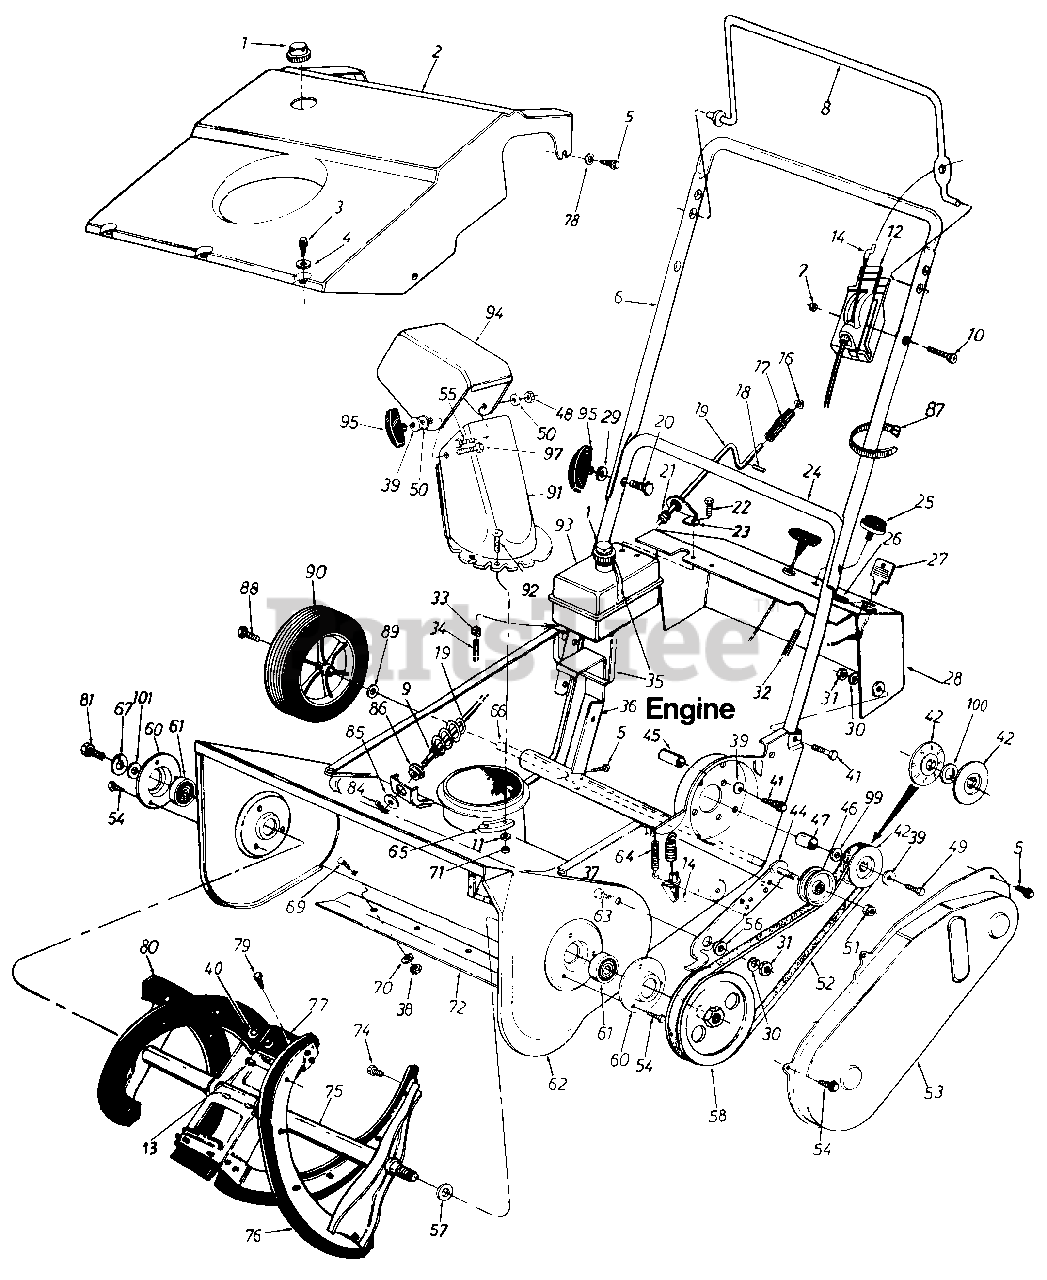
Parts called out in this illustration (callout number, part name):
1	Gas Tank Cap
2	21" Shroud
3	Hex B-Tap Scr. #10 x .38"
4	Spr.-Wash. .206" I.D. x .448"
5	Hex L-Wash. Hd. AB-Tap 1/4 x .62" Lg.
9	Fl-Wash. .385" I.D. x .62"
10	Oval C-Sunk Mach. Scr.
11	Fl-Wash. .281" I.D. x .5" O.D.
12	Throttle Body
13	Pop Rivet .187" Dia.
14	Clutch Cable 35" Lg.
16	Push Cap 3/8" Rod
17	Knob-3/8" Dia. Hole
18	Roll Pin 1/8" Dia. x .63" Lg.
19	Chute Crank Ass'y.
20	Curved Carriage Bolt 5/16-18 x 1.75" Lg.
21	Chute Crank Grommet
22	Hex AB-Tap Scr. 1/4 x .75" Lg.
23	Upper Chute Crank Brkt.
26	Plastic Plug
27	Plastic Key (Tech. Eng.)
28	Dash Panel Ass'y.
29	Saddle Wash. .320" I.D. x .937" O.D.
30	L-Wash. 5/16" I.D.
31	Hex Nut 5/16-18 Thd.
32	Primer Hose-11" Lg.
33	Hose Clamp-1/2" Dia.
34	Gas Line-15" Lg.
35	Cable Tie-17.75" Lg.
38	Hex Jam Nut 1/4-20 Thd.
39	Bell-Wash. 5/16" I.D.
40	Torx AB-Tap Scr. 1/4 x .62" Lg.
41	Hex Bolt 5/16-18 x 1.5" Lg.
42	3/8" "V"-Pulley Half .625" I.D. x 6.0" O.D.
46	Fl-Idler w/Flanges 2.12" O.D.
47	Spacer .635" I.D. x .89" O.D. x .57"
48	Hex L-Nut 5/16-18 Thd.
49	Hex Bolt 5/16-24 x .75" Lg.
50	Fl-Wash. .344" I.D. x 1.25"
51	Hex Patch L-Nut 3/8-24 Thd.
52	"V"-Belt
54	Hex B-Tap Scr. 1/4" x .38" Lg.
55	Carriage Bolt 5/16-18 x .75"
56	Shld. Spacer .50" Dia. x .27"
57	Fl-Wash. .510" I.D. x 1.0" O.D.
58	3/8" "V"-Pulley 1/2-20 L.H. x 6"
64	Extension Spring 1.12" Lg.
65	Chute Flange Keeper
66	Wheel Axle 1/2" O.D. x 20.6" Lg.
67	L-Wash. 1/4" I.D.
69	Carriage Bolt 1/4-20 x .50"
70	Fl-Wash. .281" I.D. x .73"
71	Hex L-Nut 1/4-20 Thd.
72	Shave Plate
74	Hex Wash. B-Tap Scr. 1/4 x .62" (Spec.)
76	Rubber Spiral-L.H.
77	Rubber Paddle
78	Flat Washer
79	Hex Wash. B-Tap Scr. #10 x .62" Lg.
80	Rubber Spiral-R.H.
81	Hex Wash. TT-Tap Cl-Scr. 1/4-20 x .75" Lg.
84	Cotter Pin 3/32" Dia. x .75"
85	Fl-Wash. .406" I.D. x 1.25"
86	Hex Bushing .385" I.D.
87	Cable Tie
88	Hex Tap Scr. 3/8-24 x .5" Lg.
89	Fl-Wash. .510" I.D. x .75"
90	Wheel & Tire Ass'y. 7" x 1.5"
91	Lower Chute
92	Truss Mach. Scr. 1/4-20 x .75"
93	Fuel Tank-One Qt.
94	Upper Chute
95	Knob Handle Ass'y.
97	Carriage Bolt 5/16-18 x 1"
99	Fl-Wash. .635" I.D. x 1.04" O.D.
100	Fl-Wash. .635" I.D. x .93" O.D.
101	Fl-Wash. .25" I.D. x .93"
